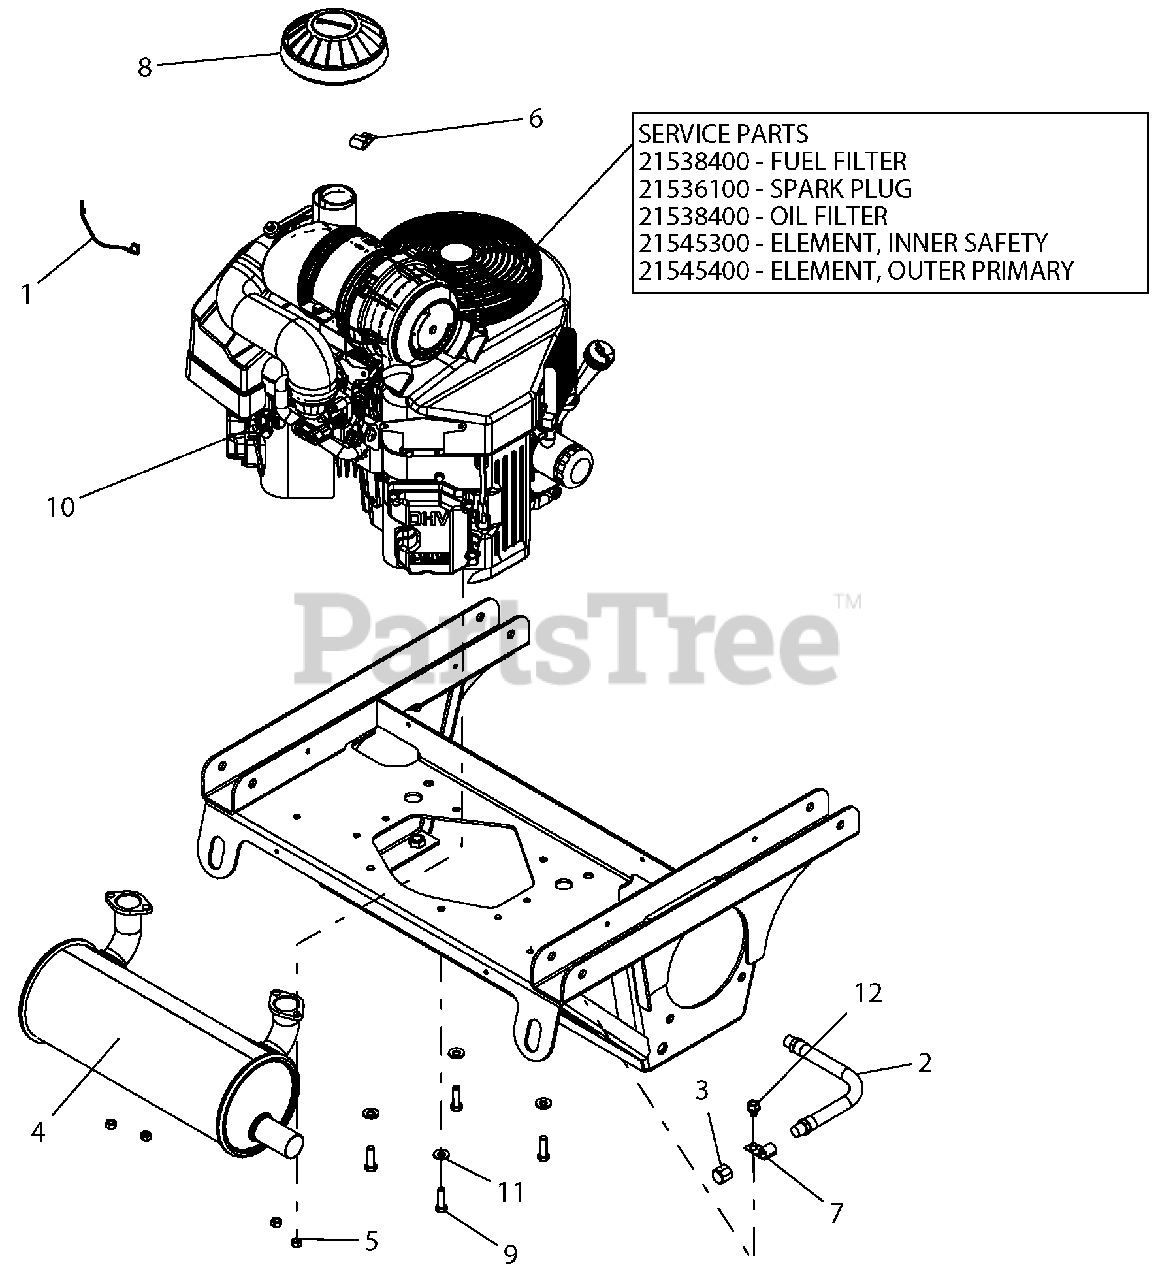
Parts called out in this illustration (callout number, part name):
1	LEAD - STARTER SOLENOID
2	HOSE, HYD .38-11-0K M6N0-M6N0
3	PIPE, CAP 3/8 NPT FEMALE
4	MUFFLER - 34HP KAWASAKI VERT
5	NUT-LK-TOP M8-1.25 YWZC
6	CLAMP, J
8	CAP, AIR CLEANER INTAKE (2")
9	BLT-HEX .38-16X1.25 GR5 YWZC NYTORQ
10	ENGINE, KAWASAKI FX921
11	WSHR, 3/8" SPRING DISC
12	SCR-TAP .38-16X.50 HWH TR YWZ
